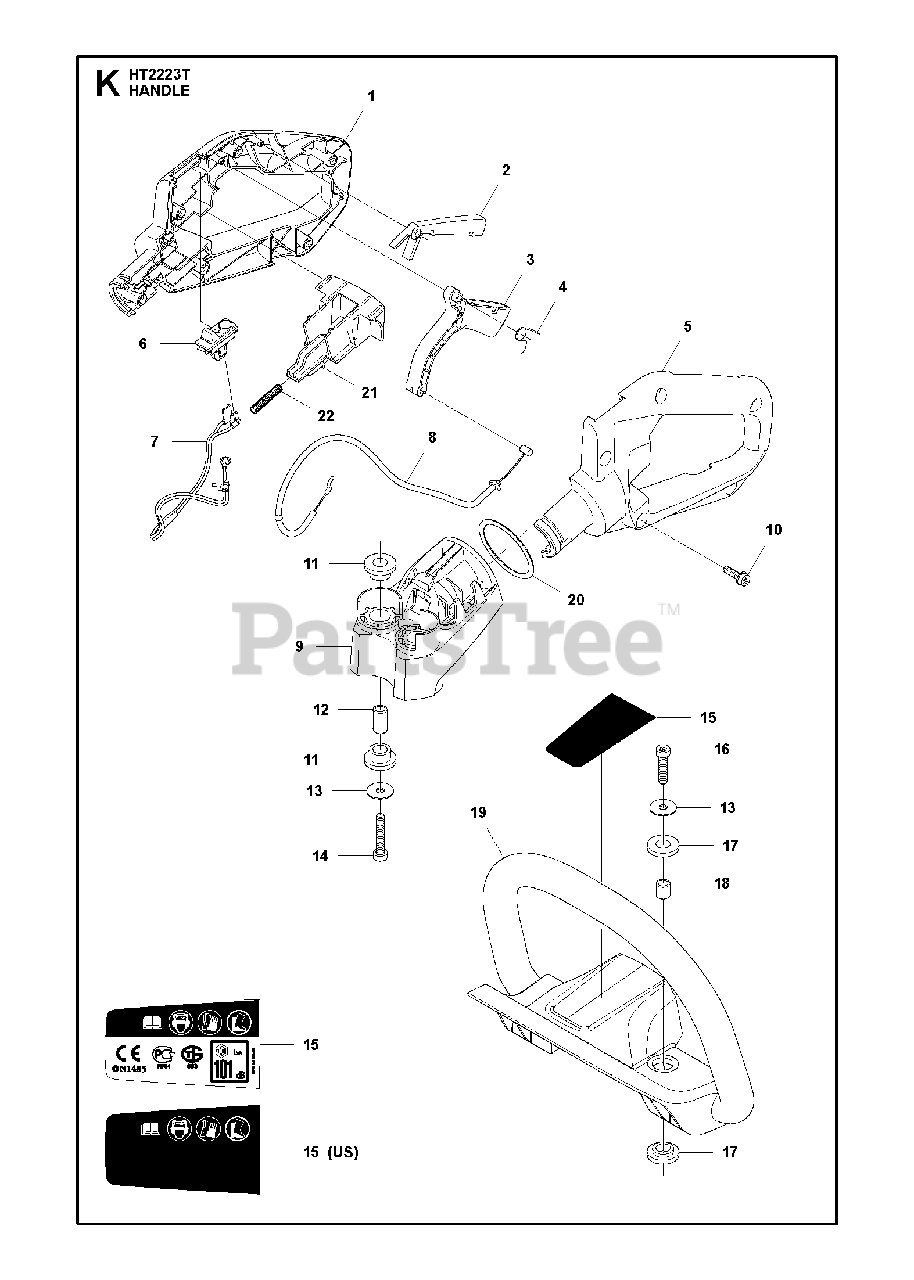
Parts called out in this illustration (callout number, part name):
1	REAR HANDLE
2	THROTTLE LOCKOUT
3	THROTTLE CONTROL
5	REAR HANDLE
6	STOP BUTTON
7	SHORT CIRCUIT CABLE
8	THROTTLE CABLE ASSY
9	HANDLE HOLDER
11	ANTIVIBRATION ELEMENT
15	DECAL
17	ANTIVIBRATION ELEMENT
20	O-RING
22	RECOIL SPRING
